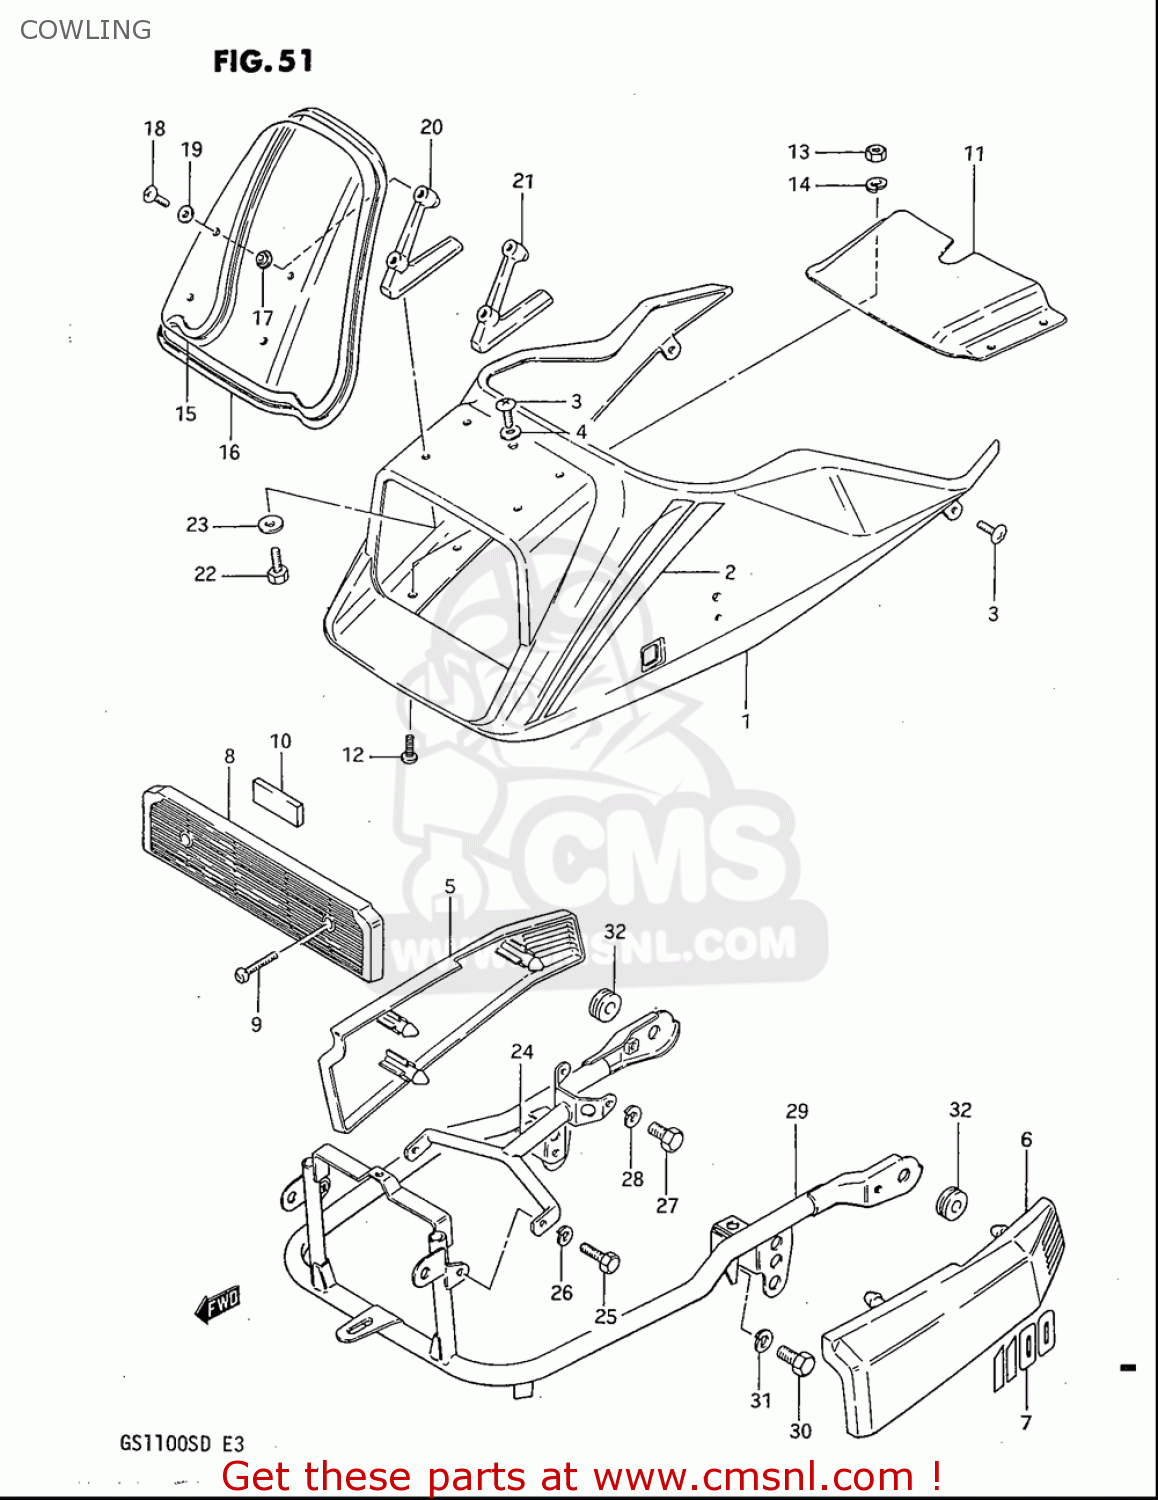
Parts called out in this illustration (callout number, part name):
1	COWLING ASSEMBLY
2	TAPE SET,HOUSING
3	SCREW
4	WASHER(6X13X2)
5	COWLING,SIDE,R(SILVER)
6	COWLING,SIDE,L(SILVER)
7	EMBLEM,SIDE COVER
8	COVER,COWLING LOWER
9	SCREW
10	CUSHION,FRAME COVER
11	COVER,COWLING LOWER FR
12	SCREW
13	NUT
14	WASHER,LOCK
15	WINDOW,COWLING
16	MOLD,COWLING
17	CUSHION
18	SCREW
19	WASHER(5.2X11X1)
20	BRACE,COWLING WINDOW RH
21	BRACE,COWLING WINDOW LH
22	BOLT
23	WASHER(6.5X16X1.2)
24	BRACKET,COWLING UPPER
25	BOLT
26	WASHER,LOCK
27	BOLT
28	WASHER,LOCK
29	BRACE,COWLING RR
30	BOLT
31	WASHER,LOCK
32	CUSHION
